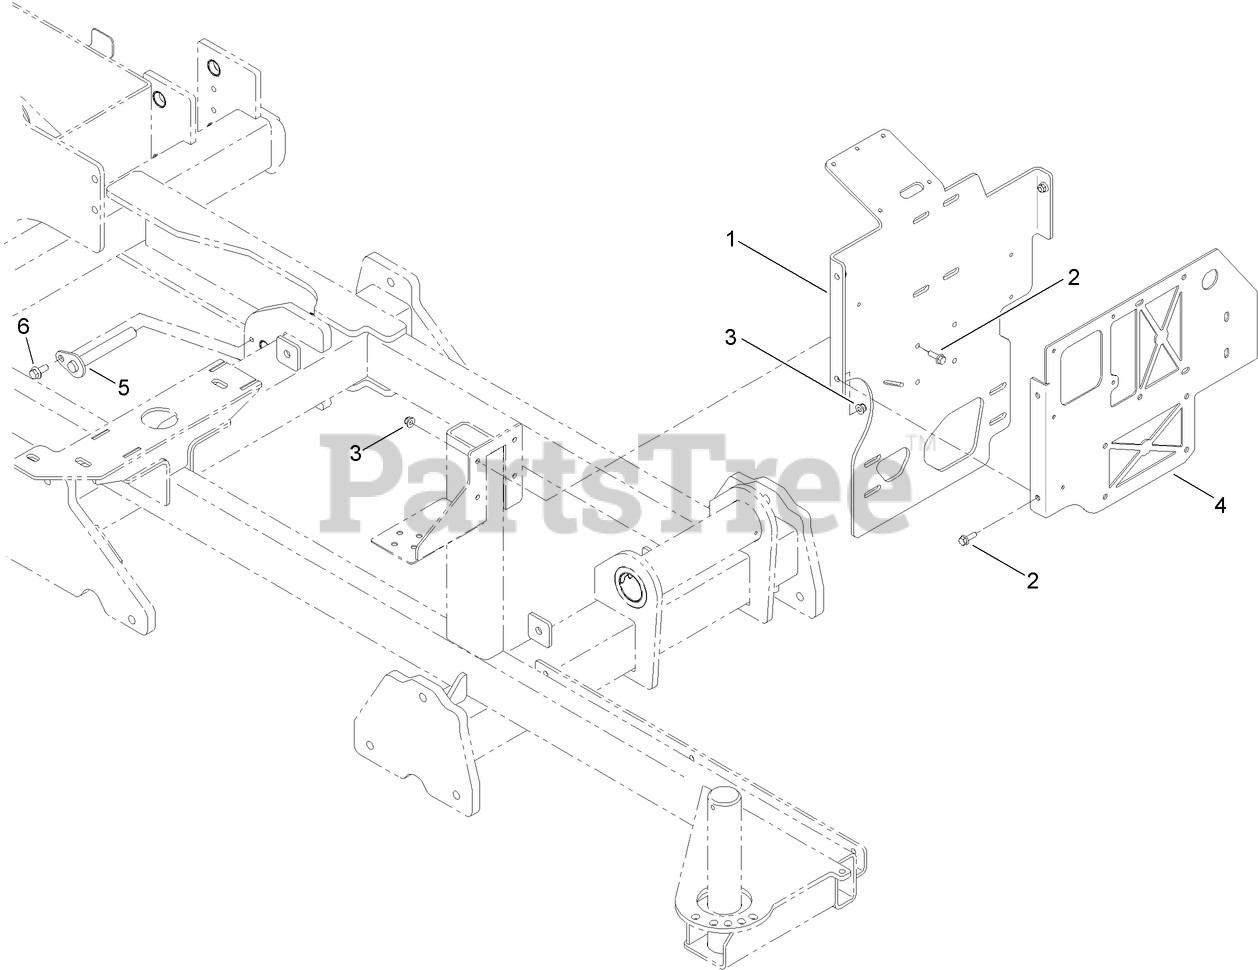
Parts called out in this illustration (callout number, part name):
1	PLATE-MOUNT, FUSE BOX
2	SCREW-HHF
3	NUT-LOCK, HHF
4	PLATE-MOUNTING, ELECTRICAL
5	PIN-FLAGGED
6	SCREW-HHF
